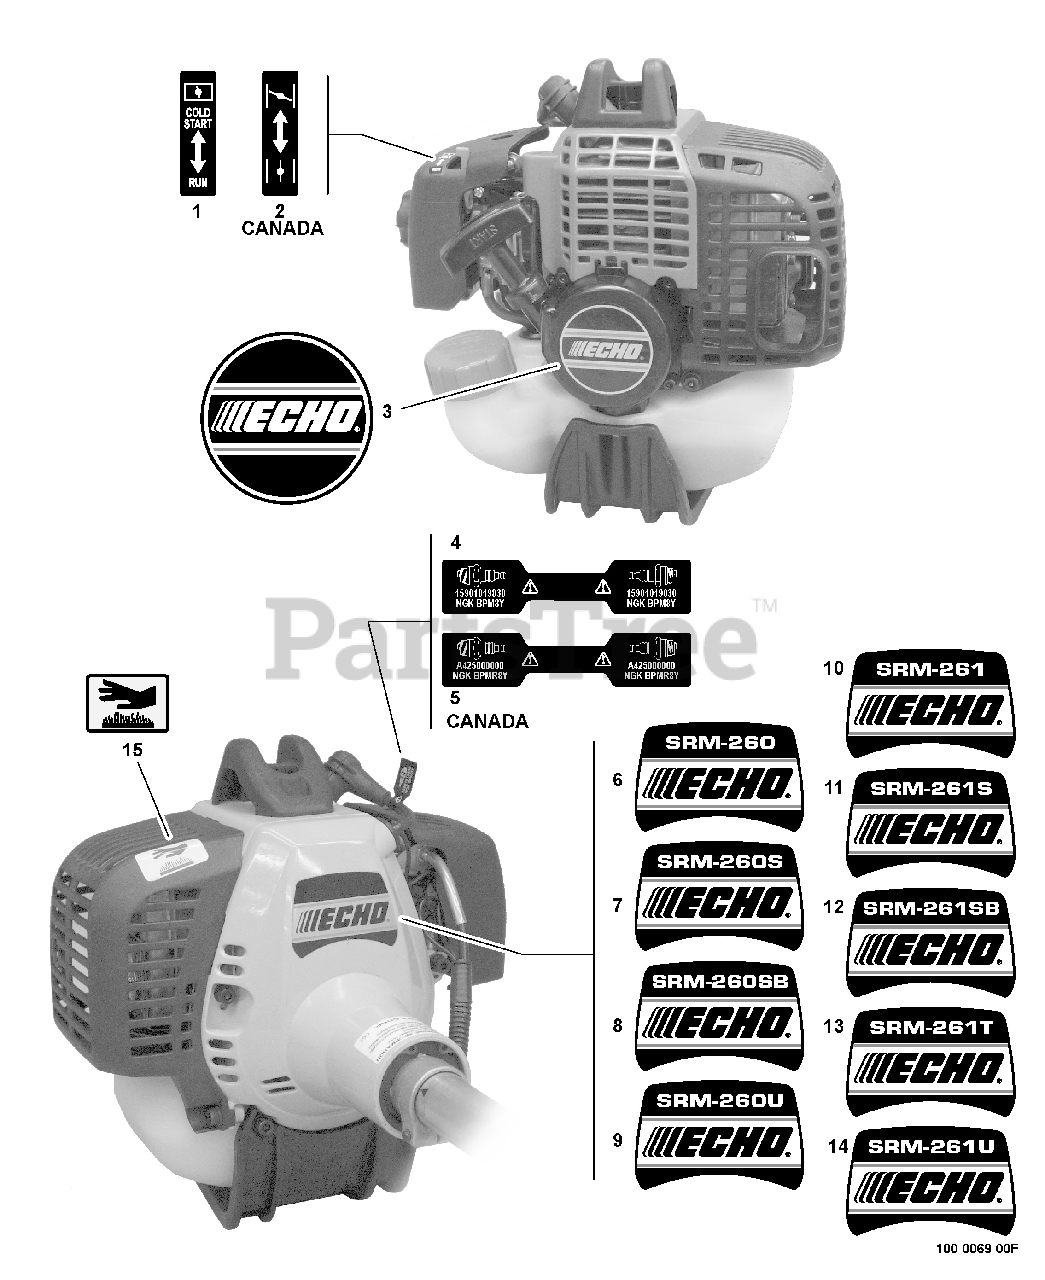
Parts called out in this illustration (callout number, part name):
1	LABEL - CHOKE
2	LABEL - CHOKE
3	LABEL - ECHO
4	LABEL - MODEL SRM-260
5	LABEL - MODEL SRM-260S
6	LABEL - MODEL SRM-261
7	LABEL - MODEL SRM-261S
8	LABEL - MODEL SRM-261SB
9	LABEL - HOT SURFACE
